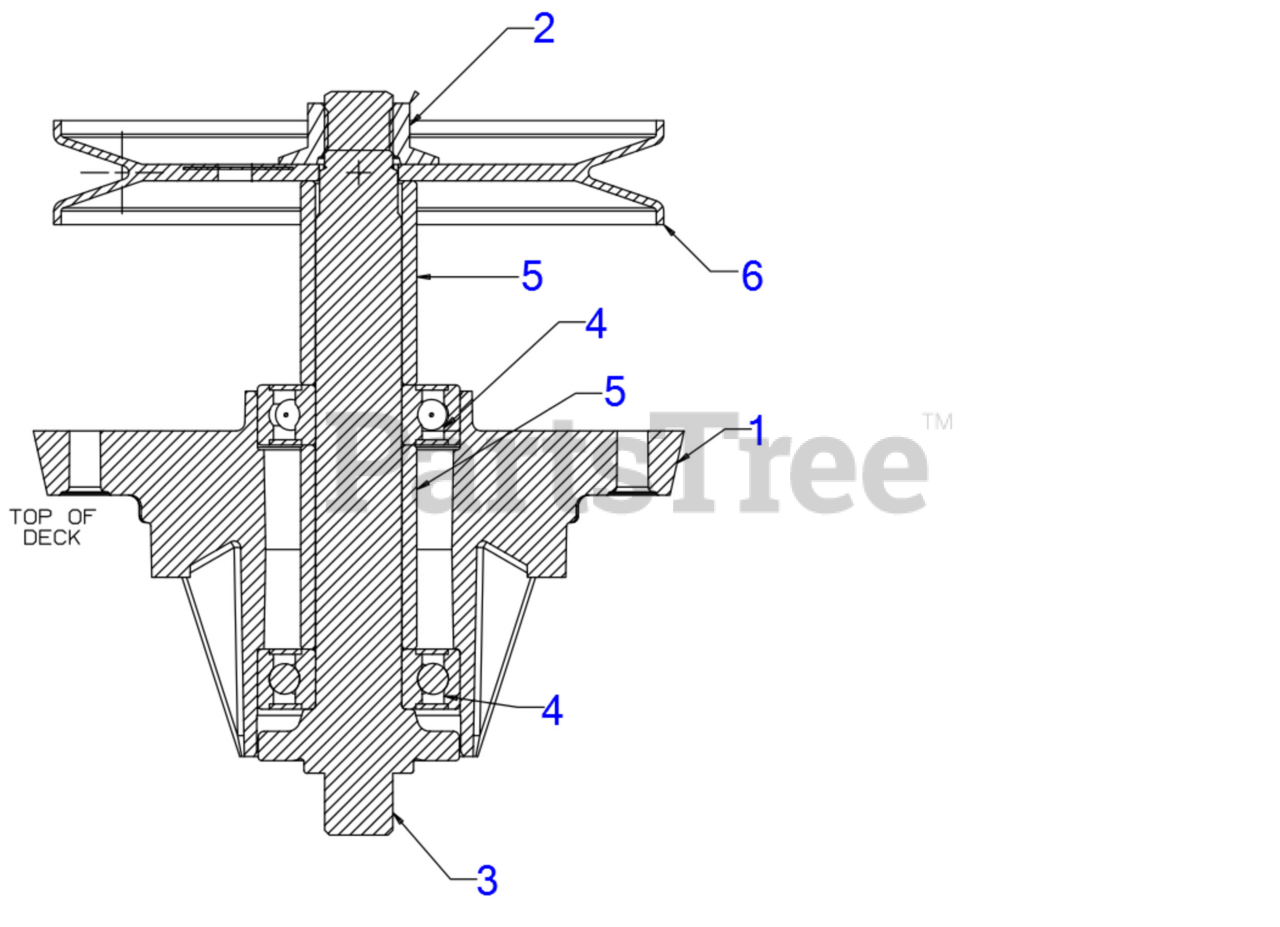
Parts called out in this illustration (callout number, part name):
1	DECK SPINDLE HOUSING
2	HEX NUT
3	BLADE SPINDLE SHAFT STAR 6.11 LG
4	BALL BEARING
5	SPACER- .792 x 1.060 x 1.860
6	DECK PULLEY 5.4" DIA
